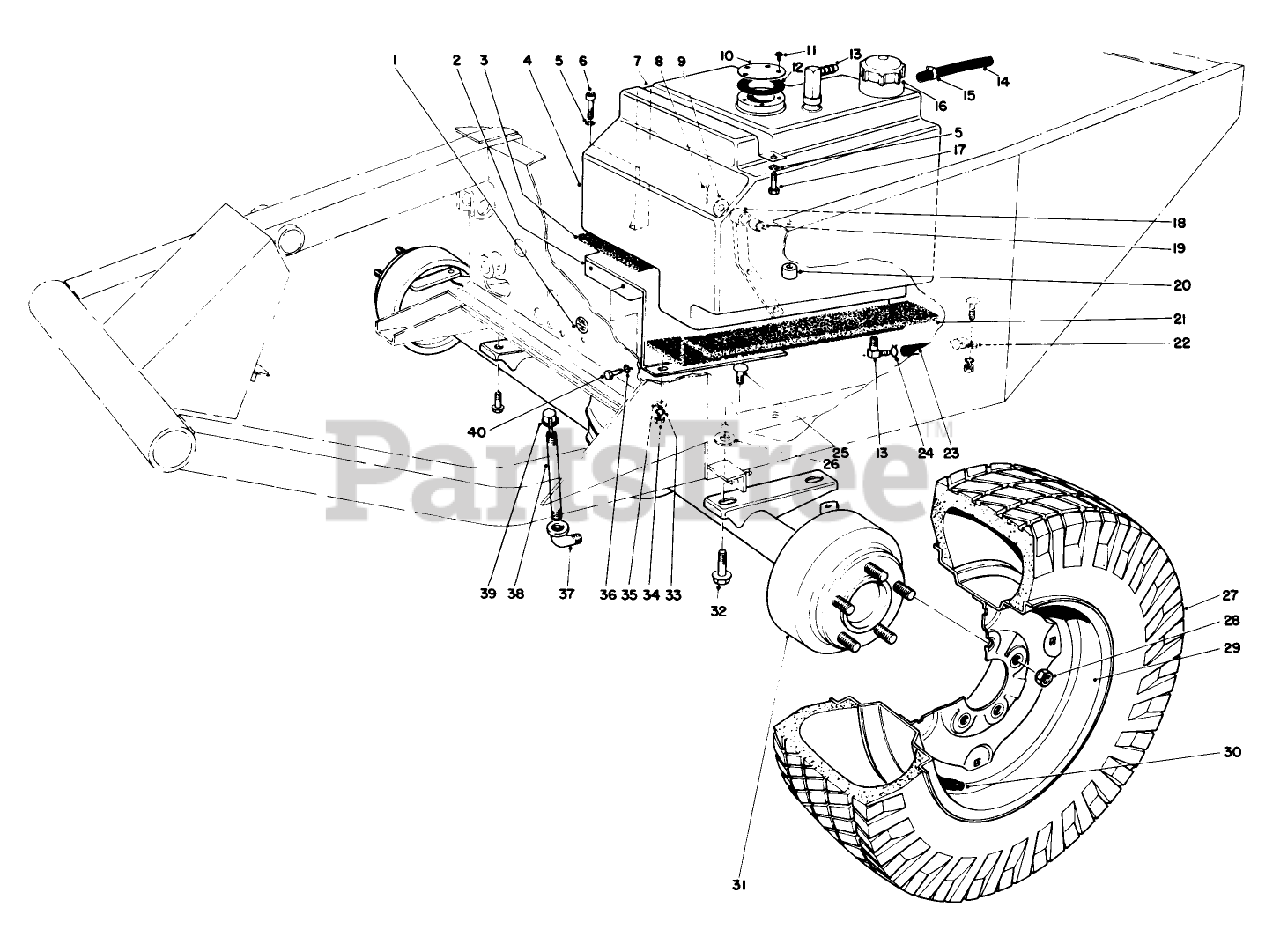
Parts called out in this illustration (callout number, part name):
1	OIL DECAL
2	GAS TANK BASE WA
3	FOAM-SUPPORT, TANK
4	Gas Tank (Incl. Ref. #13)
5	WASHER-LOCK
6	SCREW-HSH
7	STRAP-TANK, FUEL
8	PIN-COTTER
9	WASHER-THRUST
10	COVER FUEL TANK OPEN
11	SCREW-HWHTF
12	Gasket
13	FITTING-ELBOW, 90 DEG
14	HOSE-FUEL
15	CLAMP-HOSE
16	Gas Cap
17	SCREW-HH
18	Steering Link (Incl. Ref. #19)
19	BUSHING
20	SPACER
21	FOAM-SUPPORT, TANK
22	CLAMP-R
23	HOSE-FUEL
24	CLAMP-HOSE
25	BOLT-CARR
26	SHIM-AXLE
28	NUT-LUG
30	STEM-VALVE
31	AXLE WA RO
32	SCREW-HHF
33	WASHER-LOCK
34	NUT-HEX
35	WASHER-PLAIN
36	WASHER-LOCK
37	FITTING-ELBOW-90
38	NIPPLE-PIPE
39	DIPSTICK ASM
40	SCREW-HH, TAP
